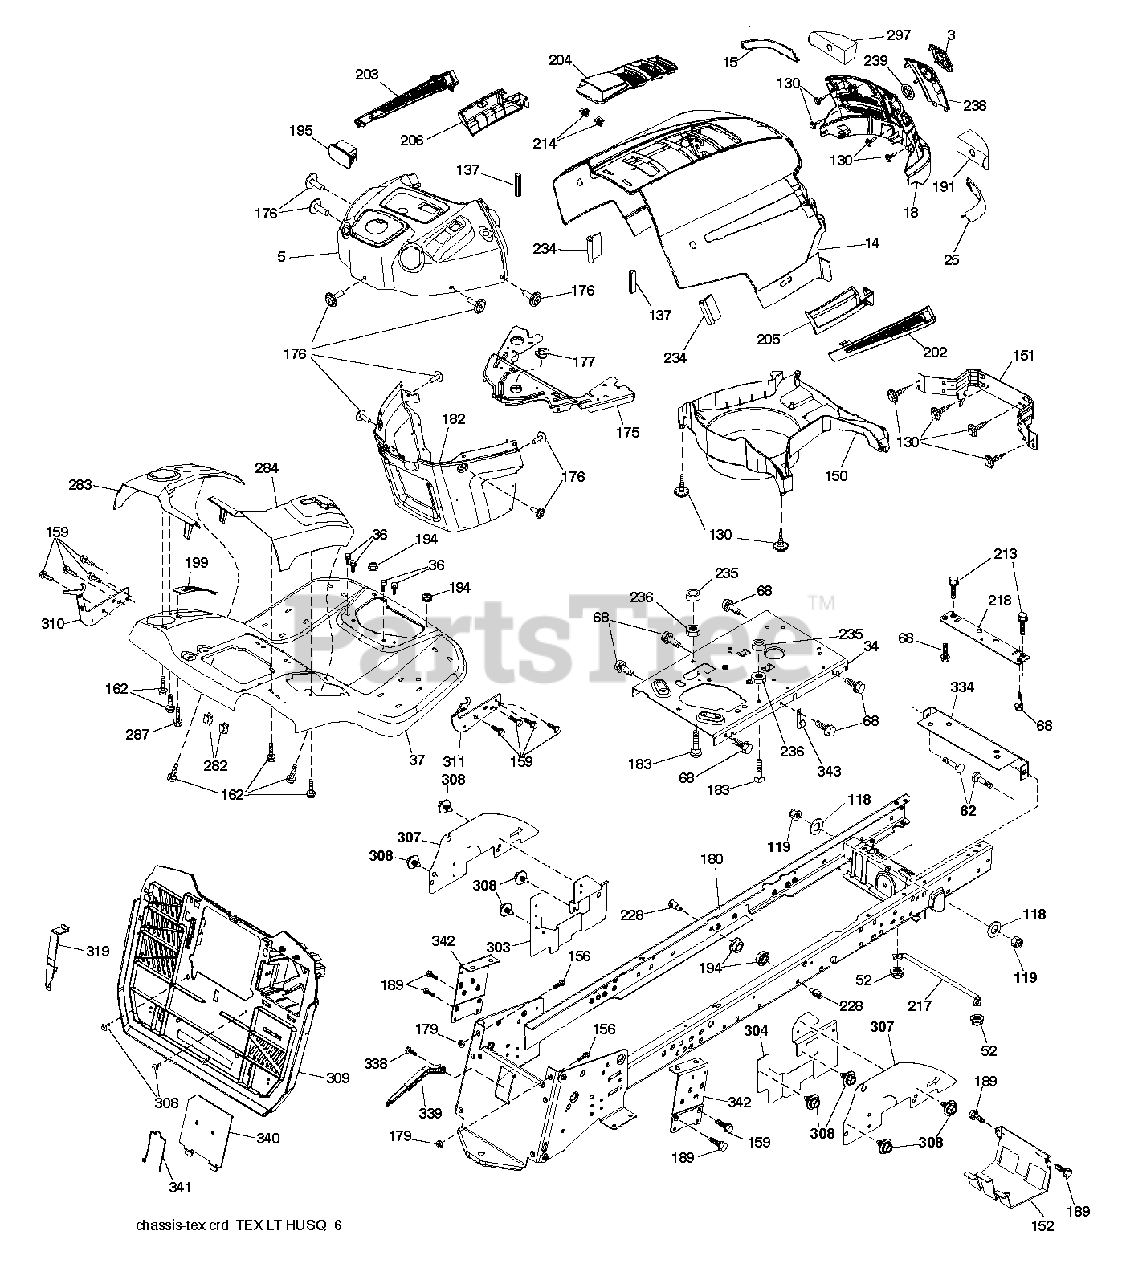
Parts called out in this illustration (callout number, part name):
3	LOGO.HUSQ.GT.LT.CROWN.H
5	DASH.UP.HU.LT.CBL.CLTCH.CHG.PT
14	HOOD.HUSQVARNA.LT.ORANGE
15	LENS.HUSQVARNA LT.RH
18	GRILLE.SVC.HUSQVARNA.GREY
25	LENS.HUSQVARNA LT.RH
34	PLATE.ENGINE.10GA.CRD.GENII
36	SCREW 5/16"
37	FENDER.TEX.SRD.CRD.FRN.GUARDS
52	LOCKNUT
62	BOLT D
68	SCREW LT
118	WASHER
130	SCREW.#10 X 0.750.BOS
137	BUMPER DASH
151	BRACKET PIVOT
152	SHIELD.BROWNING.W/TEX
159	SCREW, 3/8-16X3/4
162	SCREW.HI-LO.CONSOLE
175	CROSSMEMBER
176	SCREW.#10-24X5/8.RN.QU
177	BUSHING STEERING
182	DASH.LOWER.PREDATOR LT
183	BOLT.5/16-18X1-1/4 FULL THD
189	SCREW
191	INSERT.REFLECTIVE.RH.
194	NUT LOCK HEX FLANGE 5/16-18
195	PLUG.TEX.DASH.SVC.MINDER.GREY
199	PLATE DECK LIFT
202	VENT.SIDE.HUSQVARNA.LT.RT
203	VENT.SIDE.HUSQVARNA.LT.LFT
204	SUBASM.TOP.VENT.HUSQ.LT
205	SKIRT.SIDE.HUSQVARNA.LT.RT
206	SKIRT.SIDE.HUSQVARNA.LT.LEFT
213	BOLT
214	CLIP.RETAINER.TINNER.
217	ROD.PIVOT.HOOD
218	X-PIECE.HOOD.STOP.NON/
228	STUD.FASTNER.W/ANTI-ROTATE
234	BUMPER.HOOD.TEX.HUSQVARNA
235	SPACER FENDER
236	NUT.CENTERLOCK.5/16-
238	TRIM.HUSQ LT.668
282	CLIP.RETAINER.CONSOLE.LT.HUSQ
283	CONSL.DECKLIFT.LH.SRD.TEX.CRD
284	CONSL.SHFT.PEDAL.RH.SRD.TEXCRD
287	SCREW 1/4X20
297	INSERT REFLECTIVE
303	SHIELD.LWR.LH.LT.30DECK.CRDSRD
304	SHIELD.LOWER.RH.CRD.GEN.PNT
307	SHIELD.UPPER.CRD.SRD.ISO
308	BOLT, 5/16-18 X 1 3/4
309	BACKPLATE.TEX.CRD
310	LH.ADJUST.HANGER.BRACKET.ASM
311	RH.ADJUST.HANGER.BRACKET.ASM
319	BRACKET.ACTUATOR.BAGGER.SRD
334	BRACKET.ENGINE
338	BOLT BOLT SHOULDER
339	LEVER LEVER BAGGER
340	DOOR.PNT.BATTERY.TRY.TEX.CRD.
341	LATCH
342	SUPPORT SUPPORT FENDER
343	CLIP CLIP
